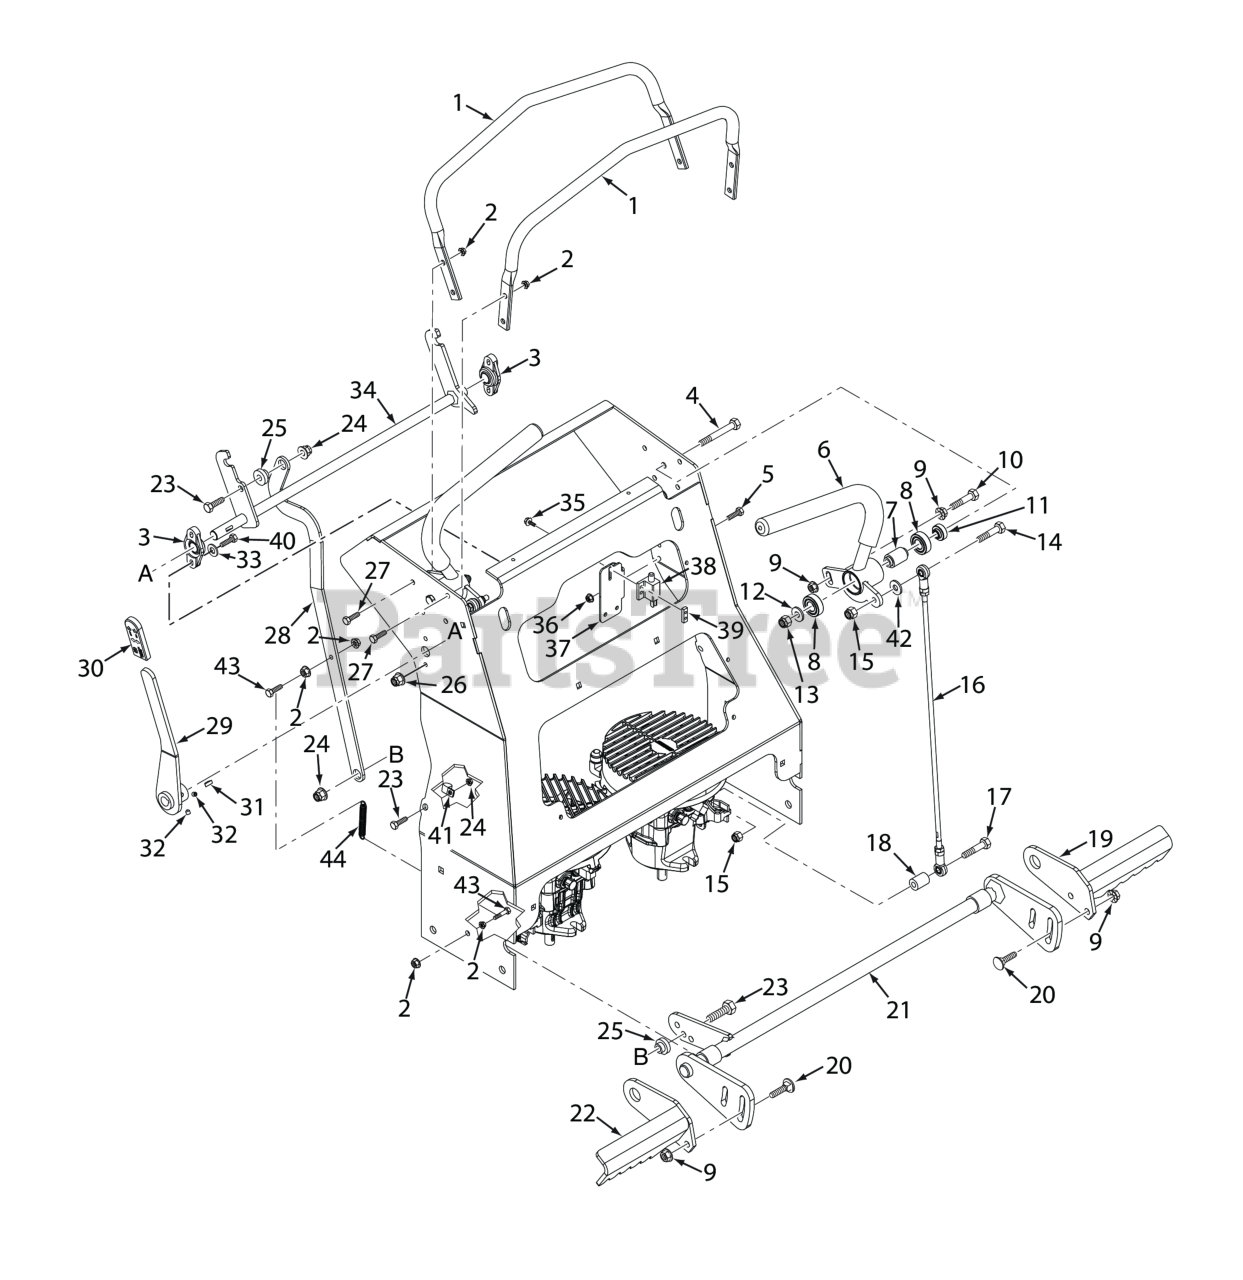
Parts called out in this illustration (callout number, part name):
1	Reference Bar
2	Nut, Serrated Flange 5/16-18 (Right Front Engine Mounting, Briggs and Kohler Only)
3	Bearing
4	Capscrew, Hex Head 3/8-16 x 3.25"
5	BOLT, HEX HEAD, 1/4-20 X 3/4 GR.5
6	Handlebar Assy., LH
6	Handllevar Assy., RH
7	Spacer, Bearing
8	BEARINGS, BALL, NEUTRAL RETURN
9	NUT, 3/8-16 SERRATED FLANGE HEX HEAD
10	Capscrew, Hex Head 3/8-16 x 2.0"
11	Spacer, Controls
12	Flatwasher, 3/8 (.391 x .938 x .105 HD) Grade 8
13	HEX NUT, ELASTIC STOP LOCK, 3/8-16
14	Bolt, 5/16 - 18 x 1 - 1/4" Hex Head
15	HEX NUT, ELASTIC STOP LOCK, 5/16-18
16	Linkage Assy., Steering
17	Bolt, Hex Head 5/16-18 x 2-1/2" (x3) (35BV & 37BV-EFI)
18	Spacer (excludes SVRII-36A)
19	Brake Paddle Weldment, RH
20	Carriage Bolt, 3/8-16 x 1.0"
21	Bellcrank Weldment, Brake
22	BRAKE PADDLE WLMT, LH
23	Bolt, Hex Head 3/8-16 x 1-1/4", Kawasaki FX / FS
24	Nut, Flange Elastic Stop Nut, 3/8-16
25	BUSHING, BRONZE - .376 ID X .627 OD
26	Nut, Flanged Elastic Stop 1/4-20
27	BOLT, SERRATED FLANGE HEX HEAD 5/16-18 X 3/4"
28	Link, Brake Engage
29	Lever Assembly, Brake, SVRII
30	Grip, Brake Handle
31	KEY, WOODRUFF #61, 3/16 X 5/8
32	Set Screw 1/4-20 x 1/4"
33	Flatwasher, 1/4 (.281 x .625 x .065)
34	Lock Weldment, Neutral
35	Screw, Hex-Slotted Washer Head #10 32 x 3/4"
36	NUT, 1/4-20 SERRATED FLANGE HEX HEAD
37	Bracket, Neutral Switch
38	Switch, Interlock, Park Brake Normally Open
39	Plate, Threaded
40	Capscrew, Hex Head 1/4-20 x 1"
41	CLAMP, CABLE - 1.00
41	Cable Clamp, Double
42	Flatwasher, 5/16-.344 x .688 x .065 (48V / 52V)
43	Bolt, Hex Head 5/16-18 x 1-1/2" (Right Front Engine Mounting, Briggs and Kohler Only)
44	Spring, Deck Lift
